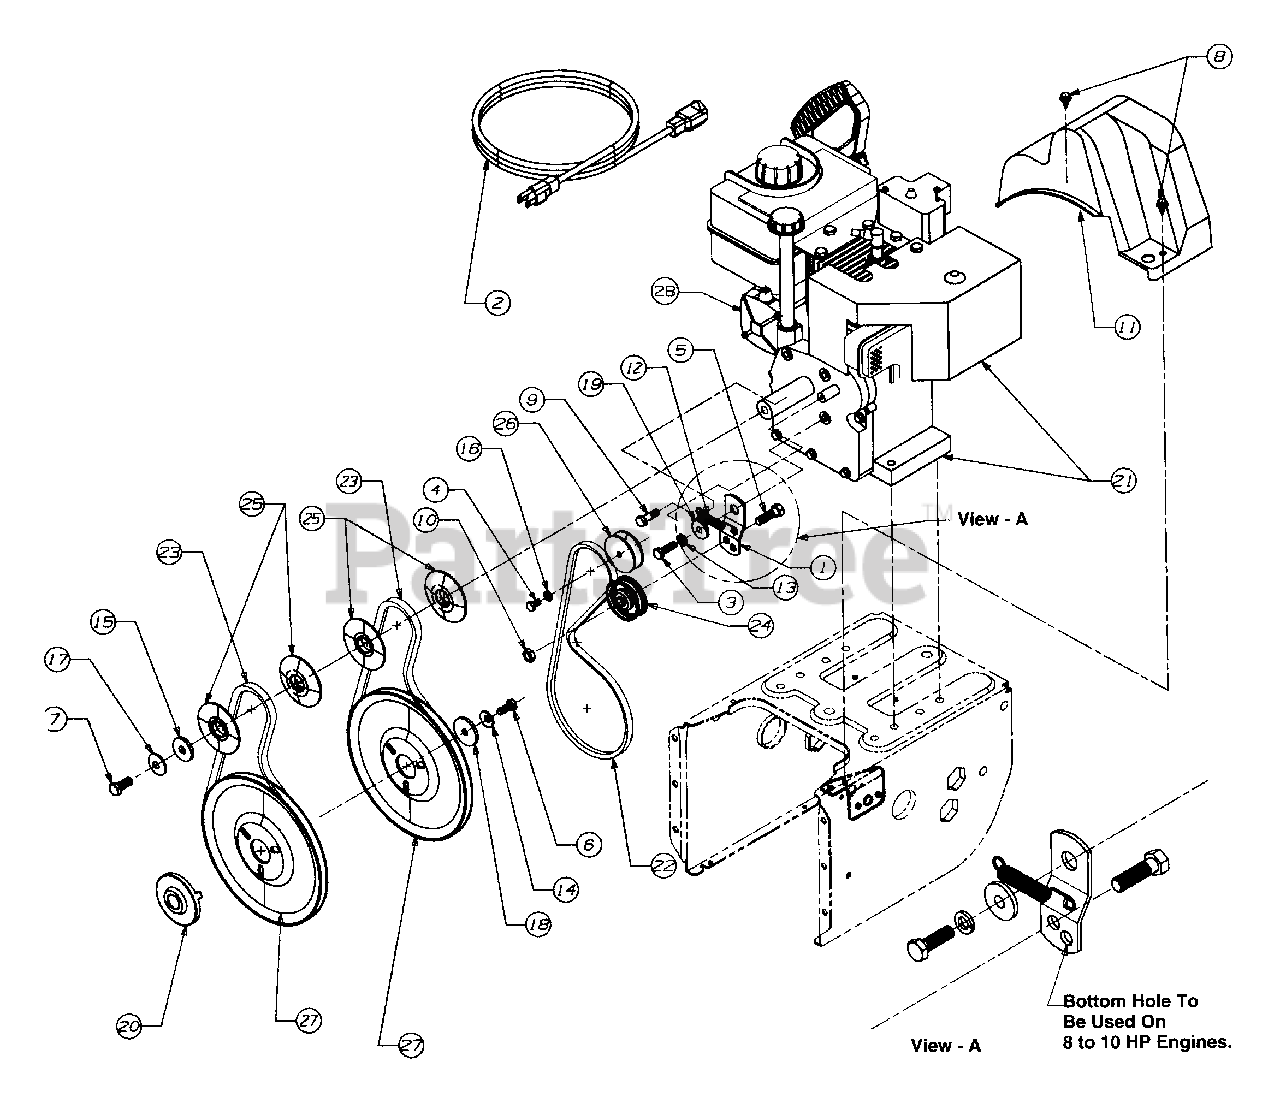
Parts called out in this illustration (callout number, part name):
3	Screw, Hex
4	Screw, Hex
5	Screw, Hex
6	Screw, Hex
7	Screw, Hex
8	Screw, Hex
9	Screw, Hex
10	Hex Jam Nut
11	Belt Cover
12	Spring
13	Lock Washer
14	Washer, Bell
15	Flat Washer
16	Washer, Lock
17	Washer, Bell
18	Washer, Flat
19	Shoulder Spacer
20	Pulley, Adapter
21	Eng., HMSK, Tec. 8.0 HP, Horz.
22	V-Belt
23	V-Belt (Matched)
24	Idler, Flat
25	Pulley, Half
26	Pulley
27	Pulley, Auger
28	Electric Start Kit
